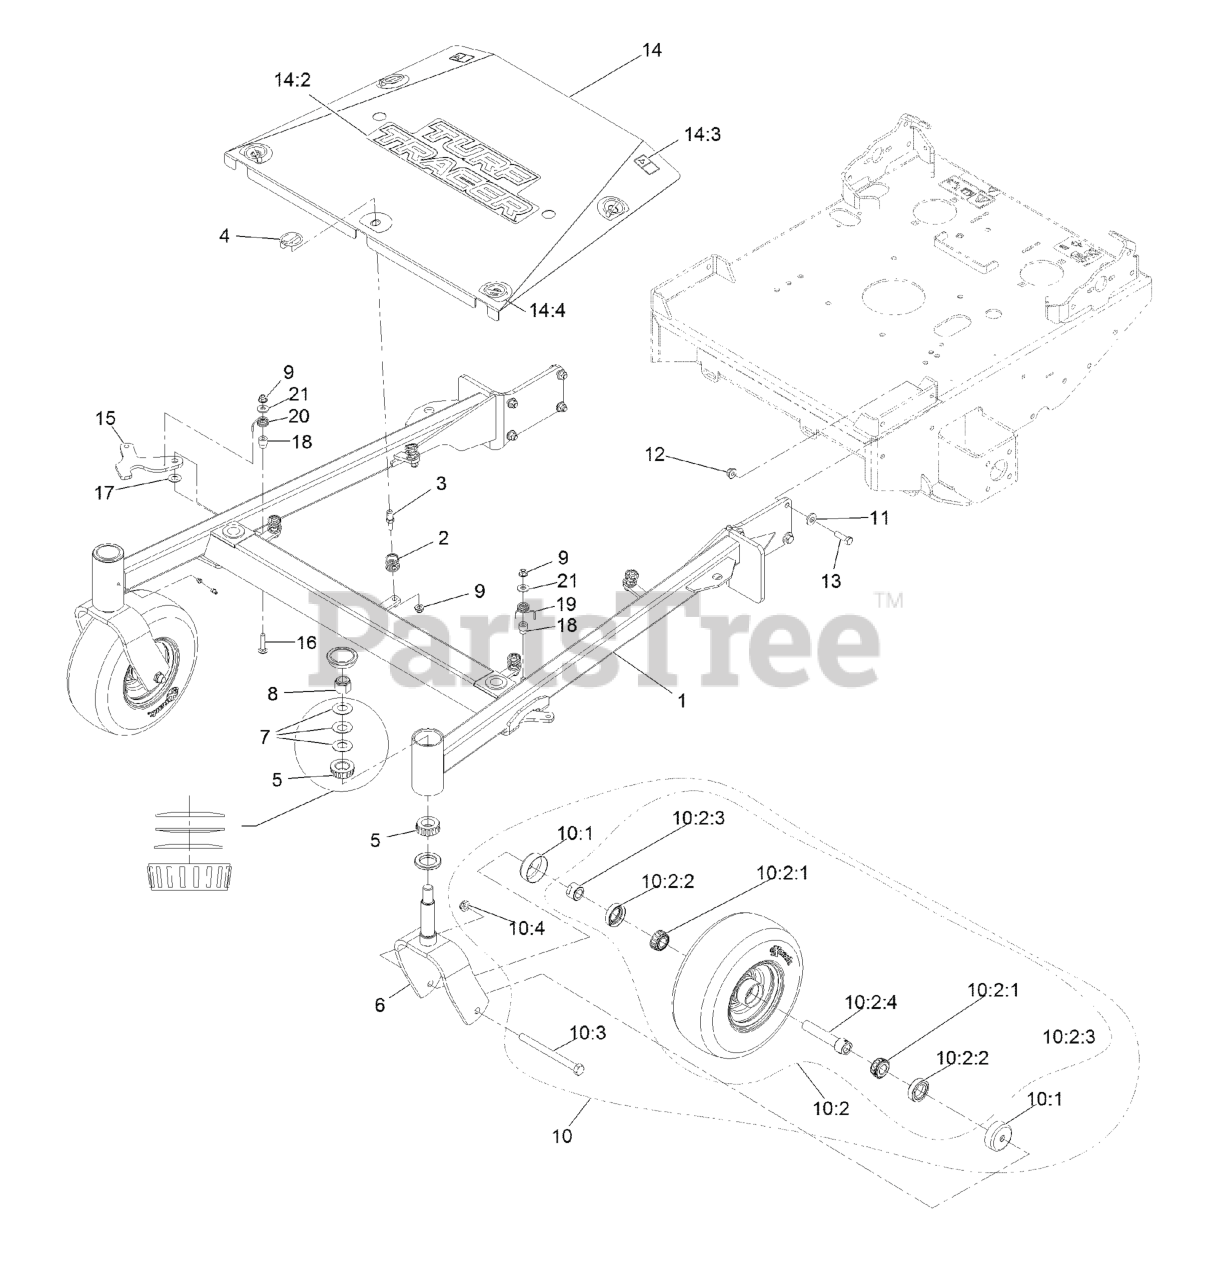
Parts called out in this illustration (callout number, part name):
1	ASM, FRONT FRAME W/ BEARI
3	PIN-SPRING
4	PIN-LYNCH
5	Cone-Bearing Tapered Roller
6	WLD, CASTER FORK
7	WASHER-BELLVILLE
8	NUT-LOCK, NI
9	NUT-HF, NI
10	ASM,WHEEL&BEARINGS
10:1	GUARD-SEAL
10:2	ASM,Wheel And Bearing
10:2:1	BEARING-CONE, TAPERED ROLLER
10:2:2	SEAL-CASTER
10:2:3	SPACER-NUT
10:2:4	CASTER AXLE ASM
10:3	SCREW-HH
10:4	NUT-HEX
11	WASHER-BELLEVILLE
12	NUT-HF, NI
13	SCREW-HH
14	ASM, CENTER SHIELD W/ DEC
14:2	DECAL-TURF TRACER
14:3	DECAL-WARNING
14:4	DECAL-SCRATCH COVER
